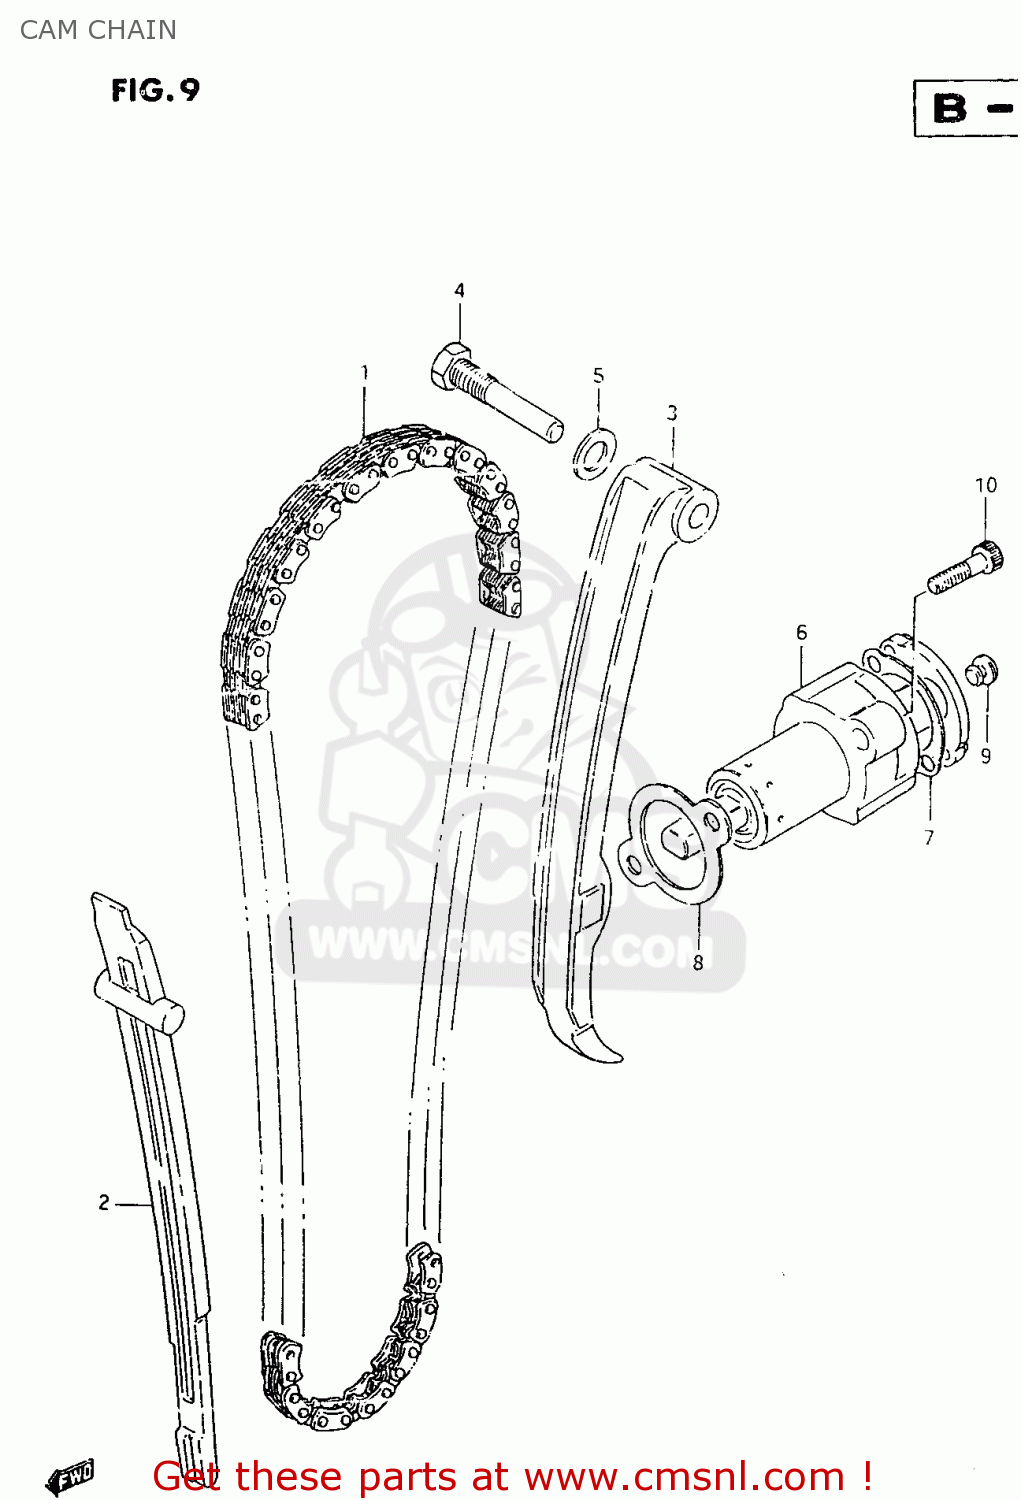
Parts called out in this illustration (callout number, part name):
1	CHAIN,CAMSHAFT DRIVE
2	GUIDE,CAM CHAIN
3	TENSIONER,CAM CHAIN
4	BOLT,CAM CHAIN TENSIONER
5	GASKET 8.2X14X1 (NAS)
6	ADJUSTER ASSY,TENSIONER
7	GASKET,ADJUSTER CAP (NAS)
8	GASKET,TENSIONER ADJUSTER (NAS)
9	PLUG,ADJUSTER
10	BOLT
